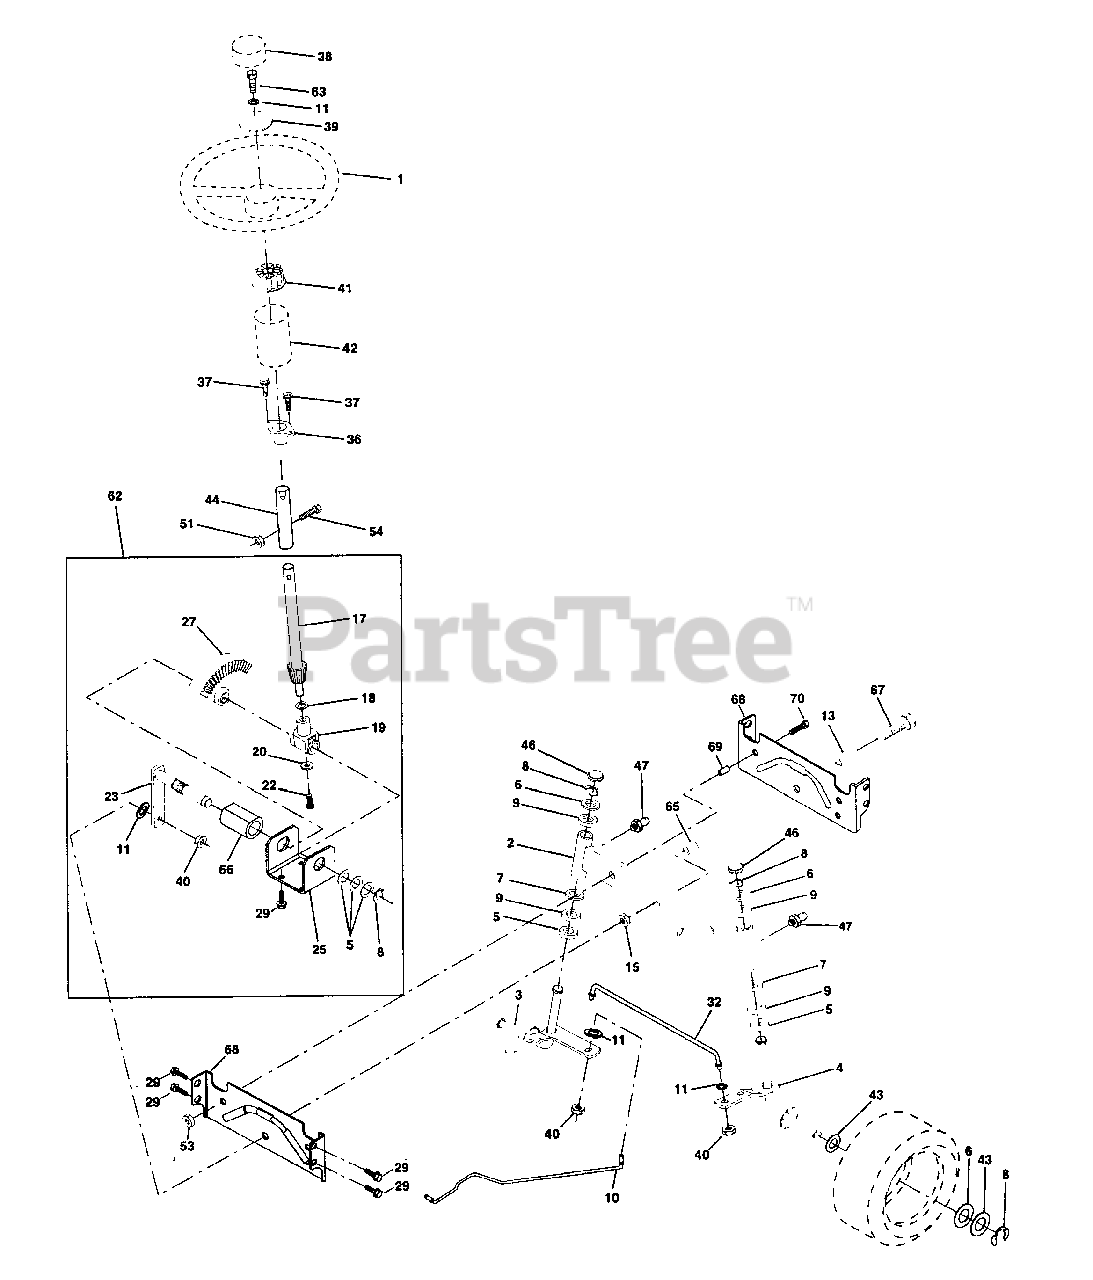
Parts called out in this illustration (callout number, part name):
1	Wheel Steering
2	Axle Front Casting Machined
3	Spindle Asm LH
4	Spindle Asm RH
5	Bearing Race Thrust Harden
6	Washer 25/32 X 1-5/8 X 16 Ga
7	Washer 27/32 X 1-1/4 X 16 Ga
8	Ring Klip #t5304-75
9	Bearing Col Strg Blk
10	Link Drag Extended Cast
11	Washer Lock Hvy Hlcl Spr 3/8
13	Bearing Axle STLT/GT
15	Nut Lock Flange 5/8-11 Unc
17	Shaft Asm Strg
18	Washer Thrust 515x 750x 033
19	Support Shaft
20	Washer Shim 1/4 X 5/8 X 062
22	Screw Hex Socket 1/4-20 X 5/8
23	Shaft Asm Pittman
25	Bracket Steering
27	Gear Sector
29	Screw Thdrol 3/8-16x3/4 Ty-tt
32	Rod Asm Tie Ball Adj. VGT
36	Bushing Strg
38	Insert Cap Strg Wh Au
39	Washer 13/32 X 2-3/8 X 8 Ga
40	Lock nut
41	Adaptor Wheel Strg
42	Boot Steering Shaft
43	Washer 25/32 X 1 1/4 X 16 Ga
44	Extension Steering Shaft LR/LT
46	Cap Spindle Fr Top Blk
47	Fitting Grease
51	Nut Lock Hex w/Ins 5/16-18
53	Nut Crownlock 3/8-16 UNC
54	Bolt Fin Hex 5/16-18 Unc x 1-1 /4
62	Kit, Steering Assembly Svc
63	Bolt Fin Hex 3/8-16unc x 1 Gr. 5
65	Spacer Axle
66	Bearing Arm Pittman
67	Bolt, Fin Hex 5/8-11 UNC x 2-3/4
68	Brace, Axle
69	Spacer Brace Axle
70	Bolt Fin Hex 3/8-16 UNC x 2-1/4
